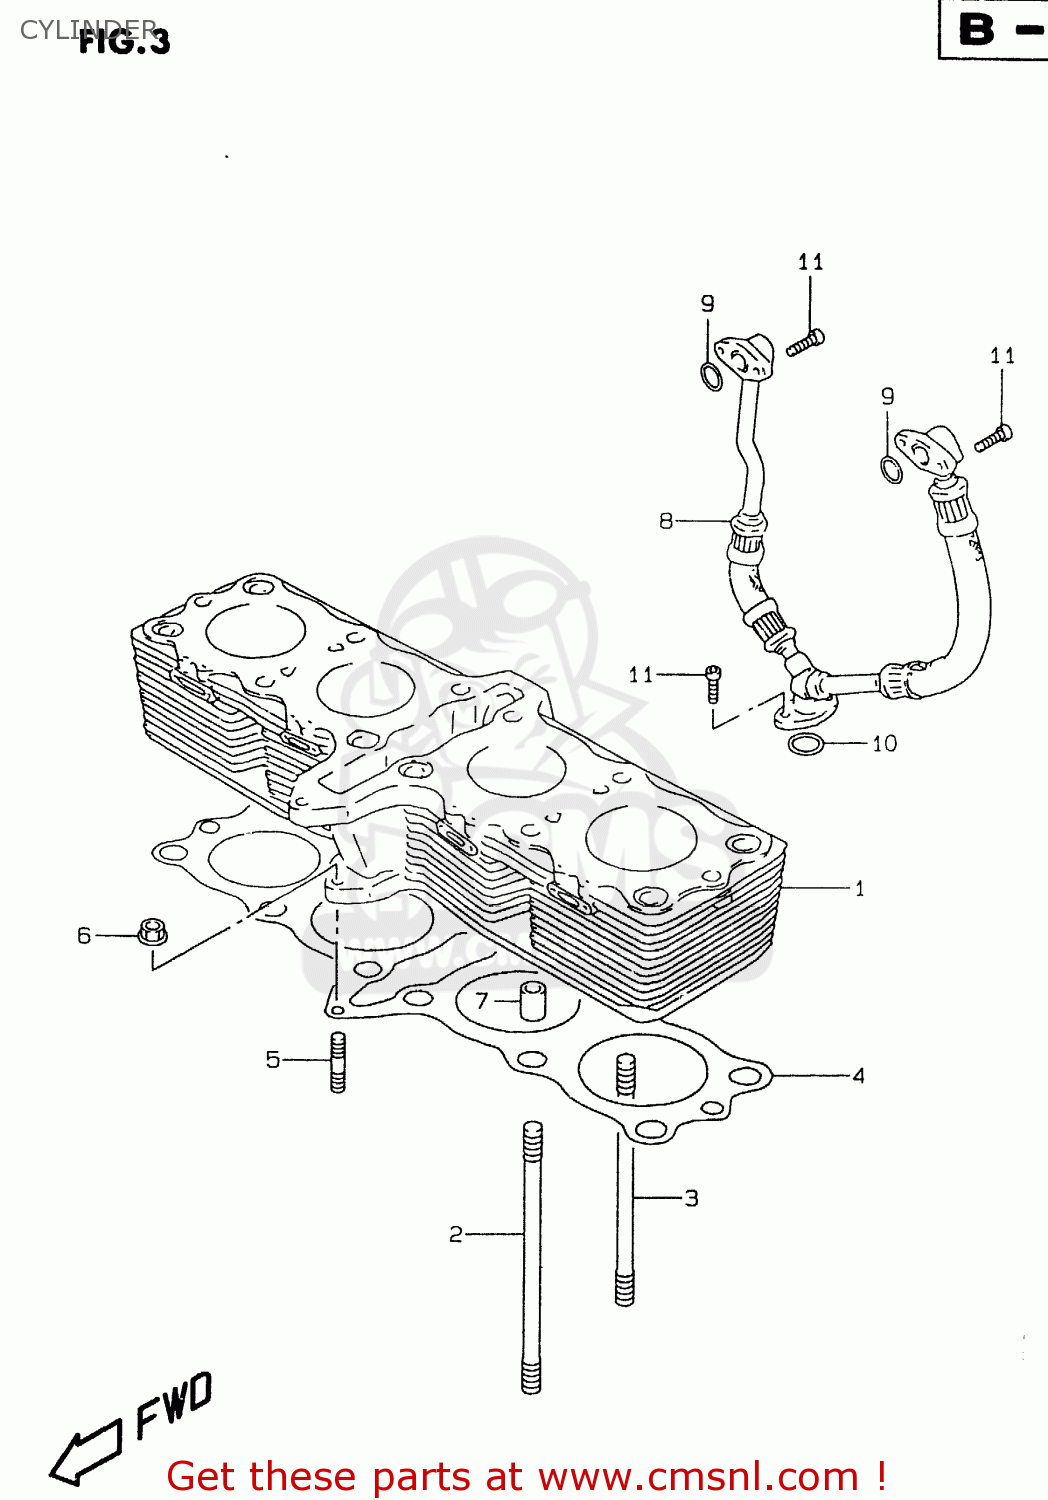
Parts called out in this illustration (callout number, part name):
1	CYLINDER COMP
2	STUD BOLT (L:150)
3	BOLT,STUD
4	GASKET,CYLINDER (NAS)
5	STUD,M6X1X32
6	NUT
7	PIN(13X10.4X20)
8	HOSE,OIL HEAD COOLER
9	O RING(D:2.5,ID:13.8)
10	O RING(D:2.4,ID:15.8)
11	BOLT,OIL FILLE
